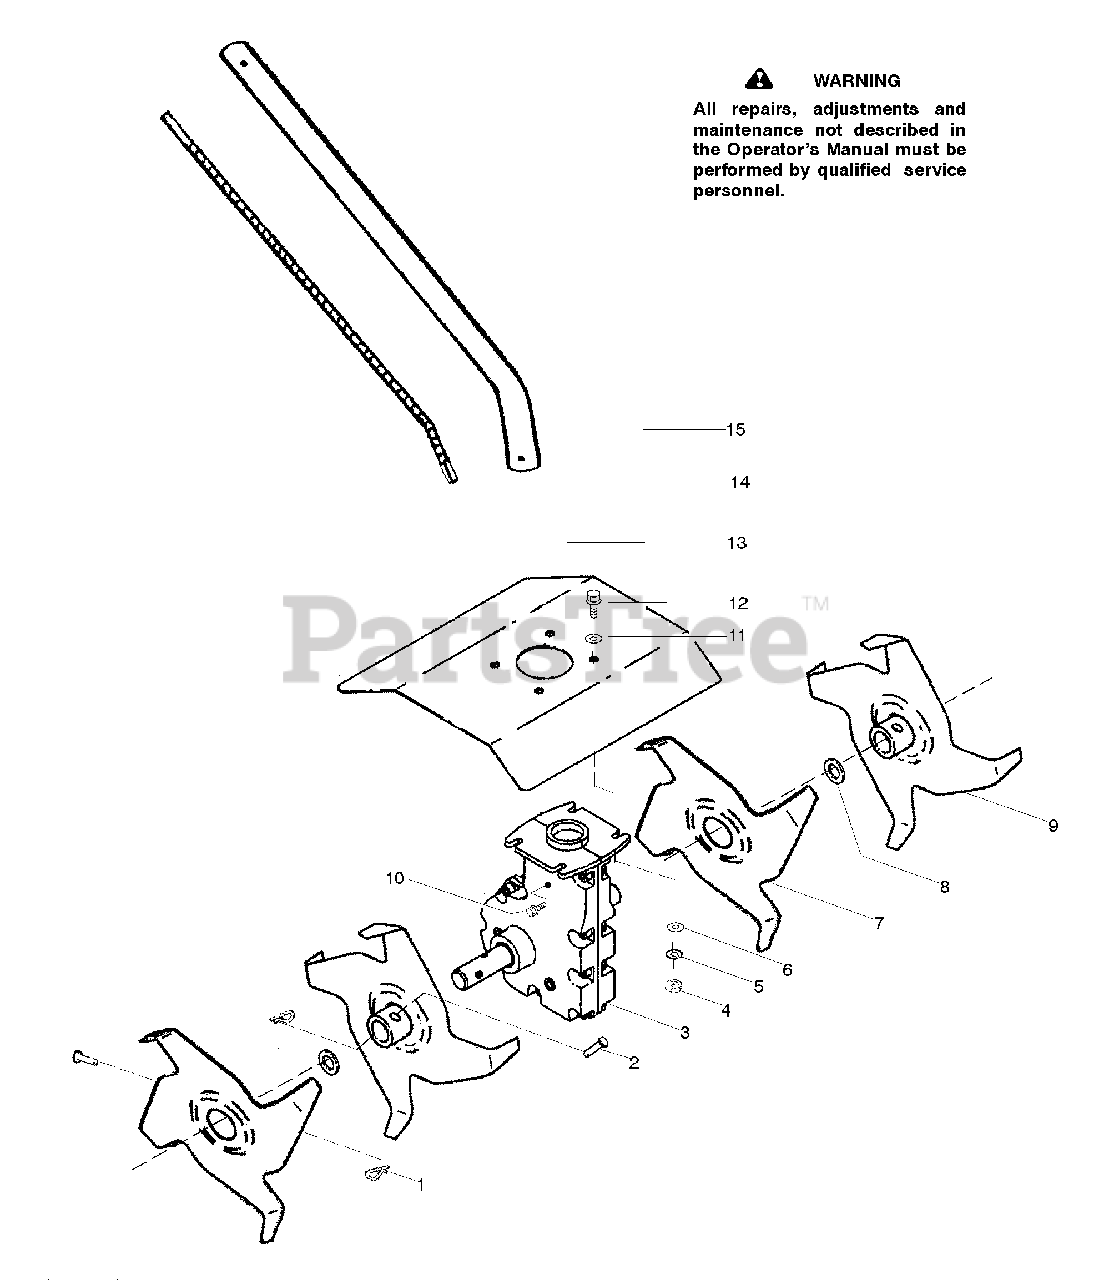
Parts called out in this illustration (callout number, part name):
1	Retainer-Hairpin
2	Pin-Clevis
3	Kit-Gearbox
5	Washer-Lock
6	Washer-Flat
7	Tine-Right Outside/Left Inside
8	Washer-Felt
9	Tine-Left Outside/Right Inside
10	Bolt-Hex
11	Washer-Flat
12	Bolt-Washer Head
13	Kit-Guard
14	Shaft-Flex
15	Assy-Driveshaft
